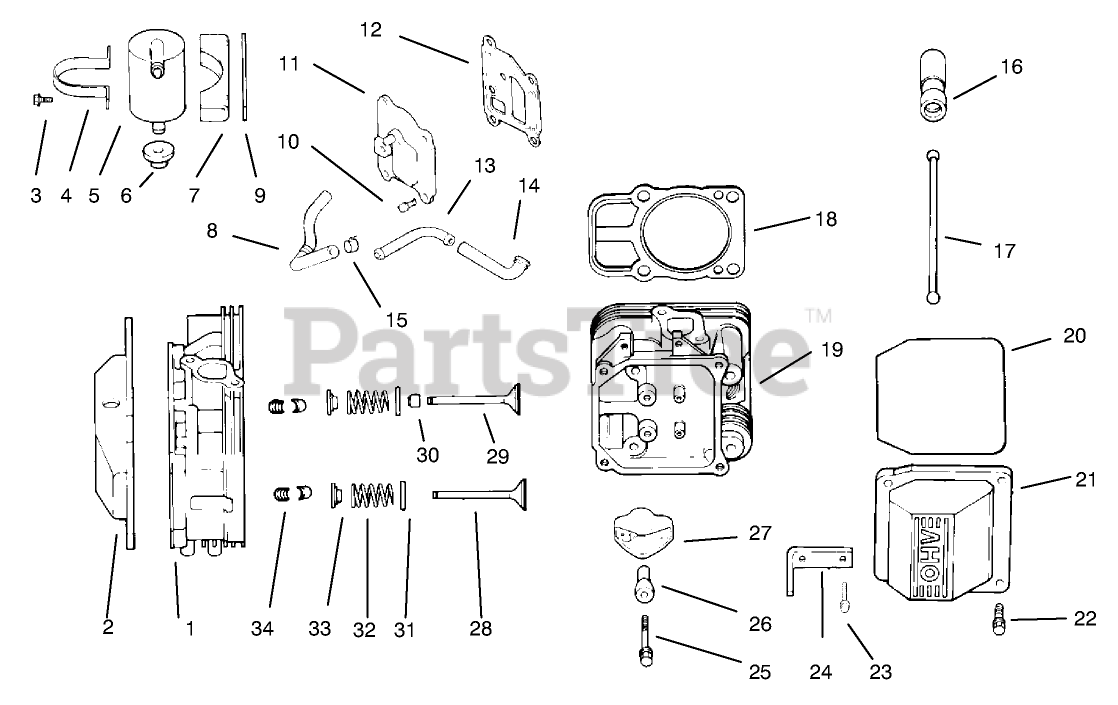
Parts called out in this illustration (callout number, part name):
1	#1 Cyl. Head Asm
2	Kit-Valve Incl 6 20-22
3	Screw-HF
4	Strap-Lifting
5	Kit-Breather Incl 3-9
6	Grommet-Rubber
7	Bracket
8	Hose-Breather
9	Spacer
10	Screw
11	Cover-Breather
12	Gasket-Breather
13	Fitting
14	Hose-Breather
15	Clamp
16	Lifter-Valve
17	Rod-Push
18	Gasket-Cylinder Head
19	#2 Cyl. Head Asm,
20	O Ring
21	Valve Kit
22	Screw
23	Screw
24	Strap-Lifting
25	Screw
26	Pivot-Arm, Rocker
27	Arm-Rocker
28	Valve-Exhaust
28	Valve-Exhaust (.25)
29	Valve-Intake
29	Valve-Intake (.25)
30	Seal-Stem, Valve
31	Retainer-Spring
32	Spring-Valve
33	Cap-Spring, Valve
34	Retainer Kit
